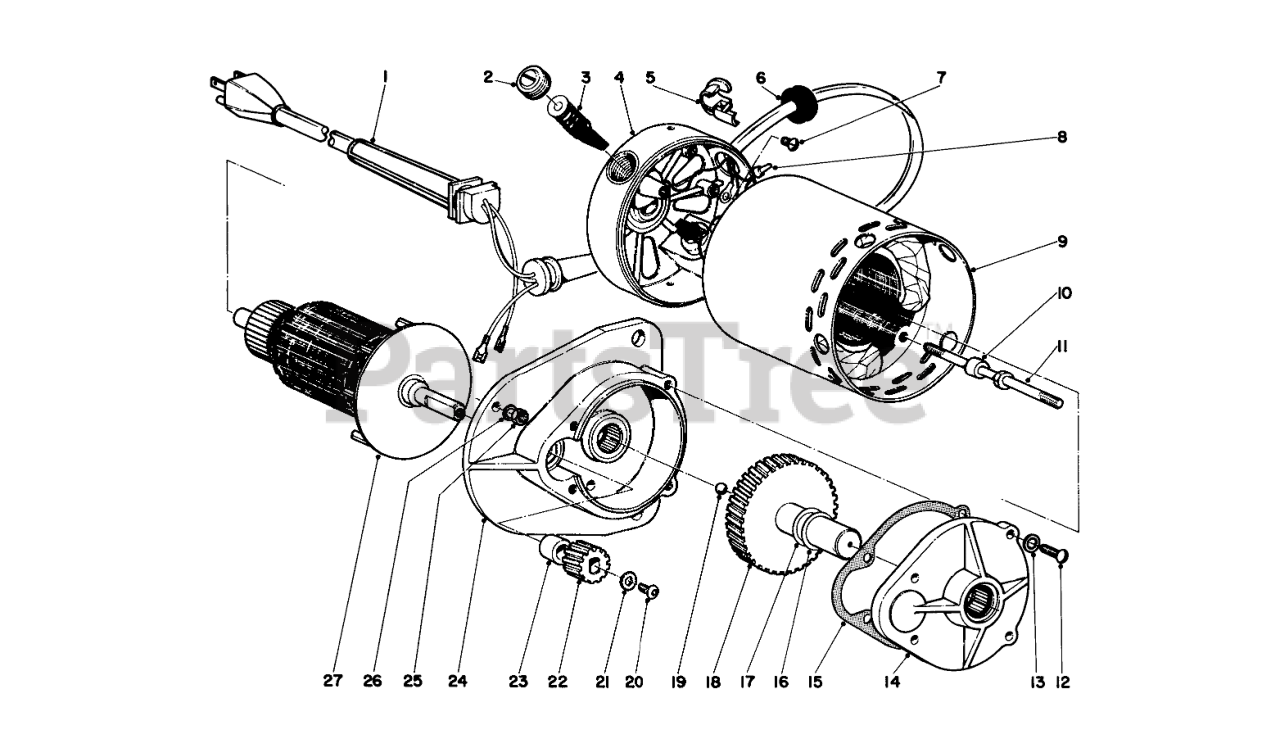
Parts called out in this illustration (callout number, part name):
2	Cap, Brush
3	Brush Assembly
4	Brush End Housing Assy.
5	Strain Relief
6	Grommet
7	Screw
8	Terminal
9	Frame & Field Assy.
10	Spacer
12	SCREW
13	WASHER-LOCK/INT
14	Gear Cover Housing
15	Gasket
16	Washer
17	Washer
18	Gear & Output Shaft Assy.
19	Ball
20	Screw
21	WASHER-FLAT
22	Pinion
23	Spacer
24	Gear Housing Assembly
26	WASHER-LOCK, INT
27	Armature Assy.
